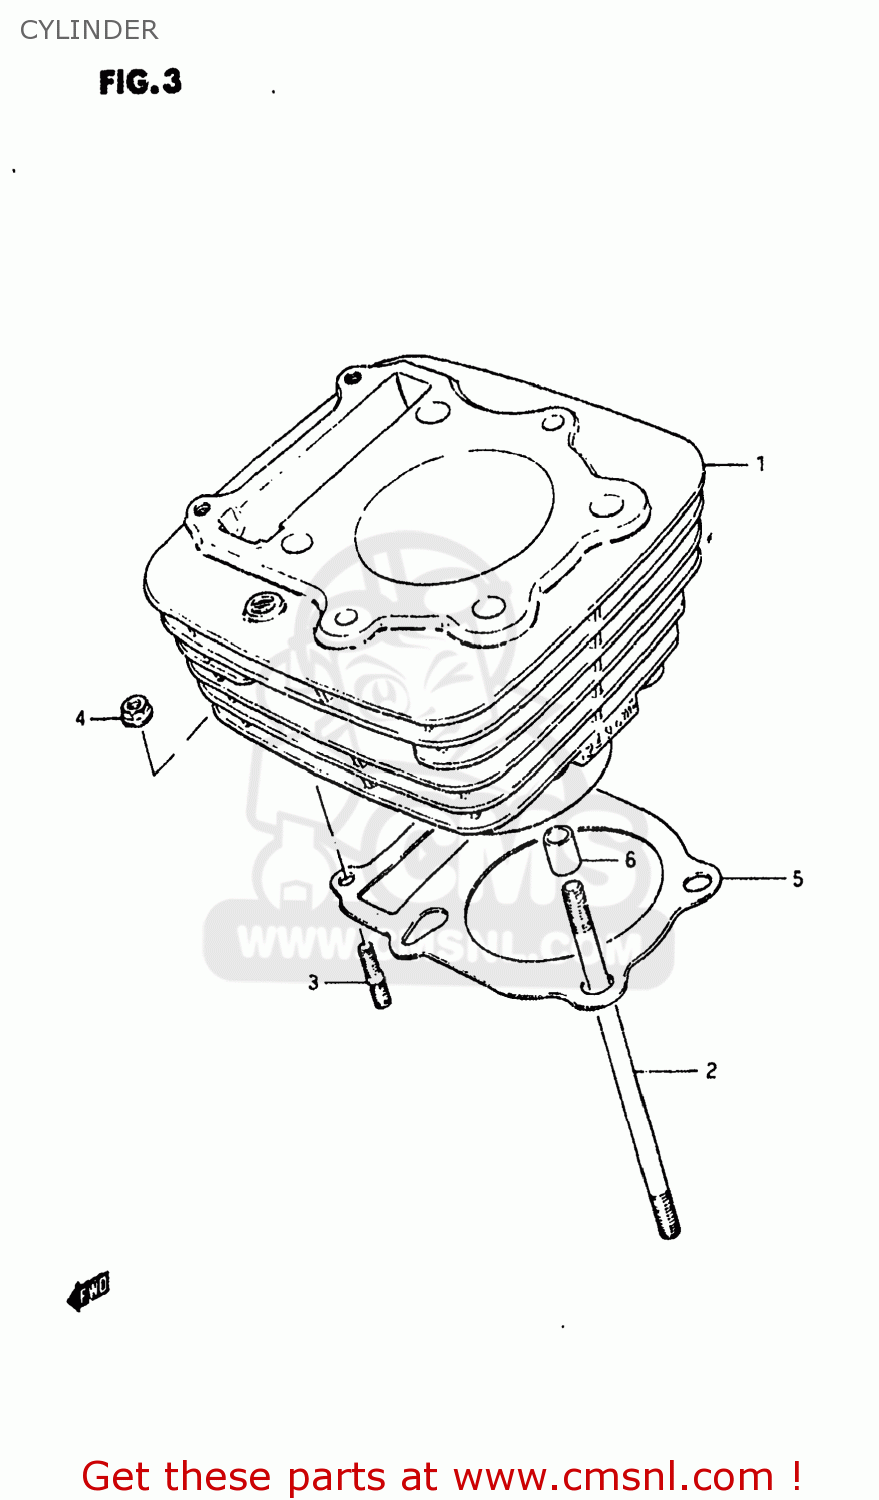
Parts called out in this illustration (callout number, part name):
1	CYLINDER
2	BOLT,STUD
3	STUD 6X25
4	NUT
5	GASKET,CYLINDER (MCA)
6	PIN
